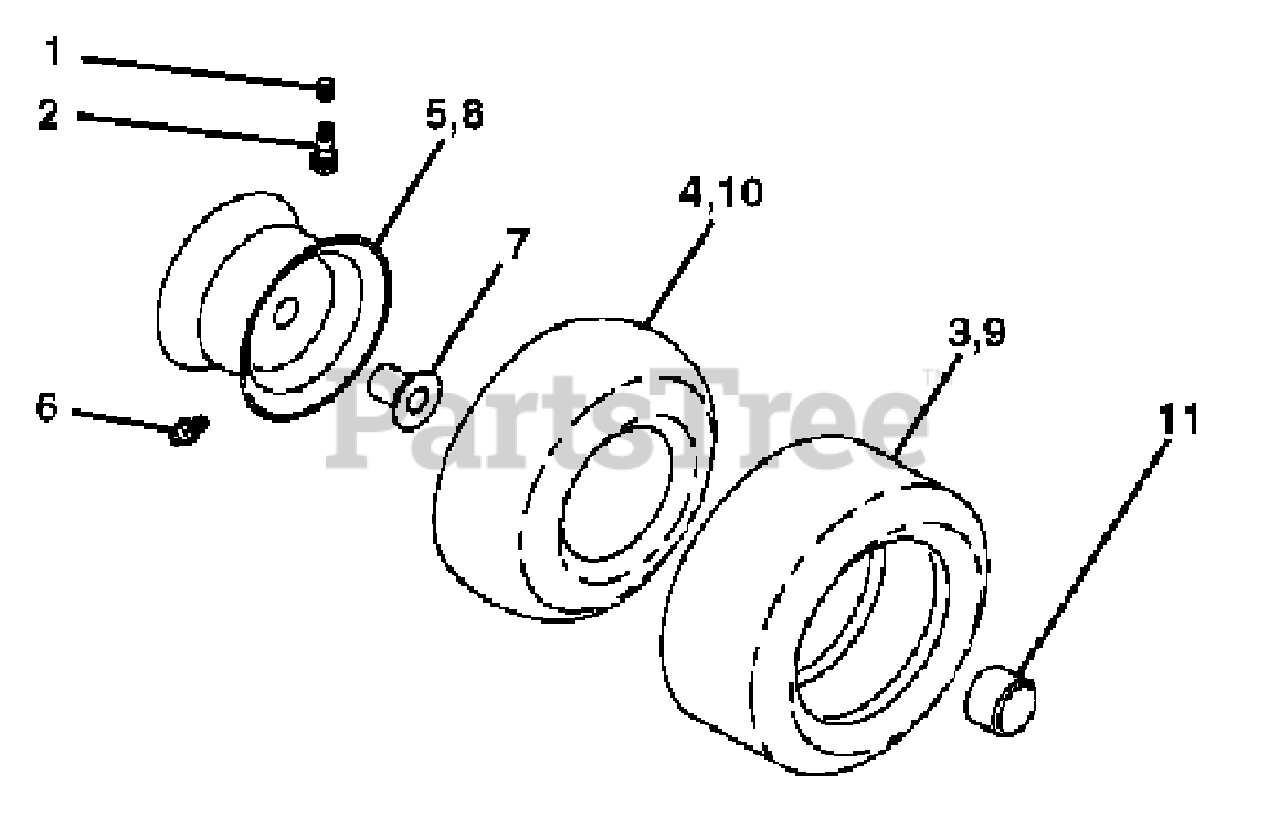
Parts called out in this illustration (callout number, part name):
1	Cap Valve Tire
2	Stem Valve
3	Tire F Ts 15 X 6 0 - 6 Service
4	Tube Front (Service Item Only)
5	Rim Asm 6"front Silver Service
6	Fitting Grease (Front Wheel Only)
7	Bearing Flange (Front Wheel Only)
8	Rim Asm 8"rear Silver Service
9	Tire R Ts 20x10-8 C Service
10	Tube Rear (Service Item Only)
11	Cap Axle Blk 1 50 X 1 00
